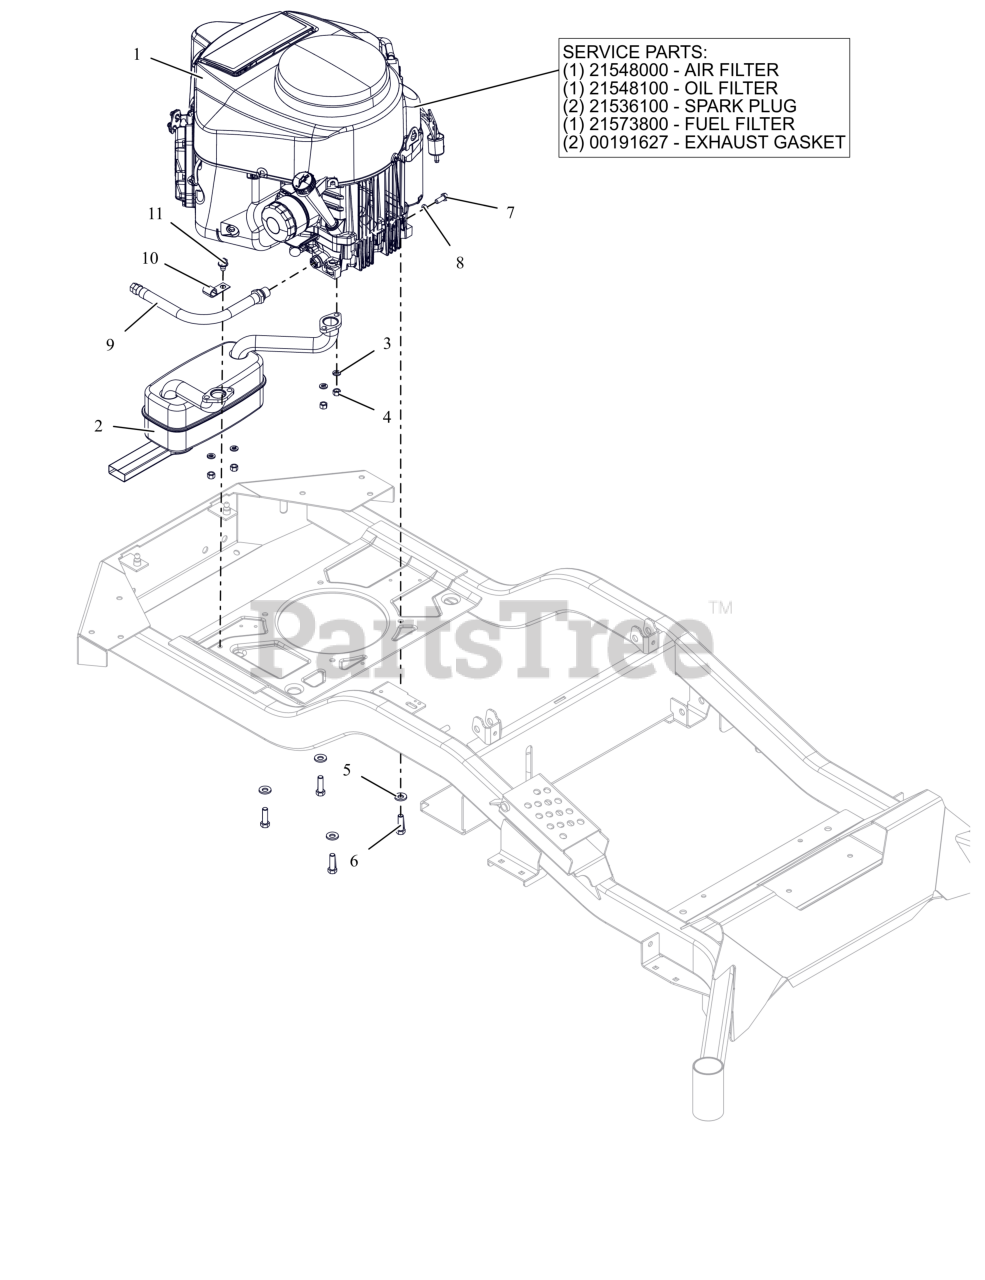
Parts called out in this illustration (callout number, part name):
1	AIR FILTER, KAWASAKI FR
1	OIL FILTER, KAWASAKI FR
1	PLUG, SPARK
1	FUEL FILTER-KAWASAKI FR
1	GASKET, MUFFLER S/O
2	MUFFLER, KAWASAKI
3	WSHR,LK-REG .312X.078 ZCC
4	NUT-LK-TOP-FLG M8 ZCC
5	WASHER, 3/8" SPRING DISC
6	BLT, HEX .38-16X1.25 G5 ZCC NT
7	BLT, HEX M8-1.25X20 G8.8 ZCC
8	WSHR,LK-REG .312X.078 ZCC
9	HOSE, OIL DRAIN
10	J-CLAMP
11	SCR,TAP .375-16X.50 HWH TR ZCC
